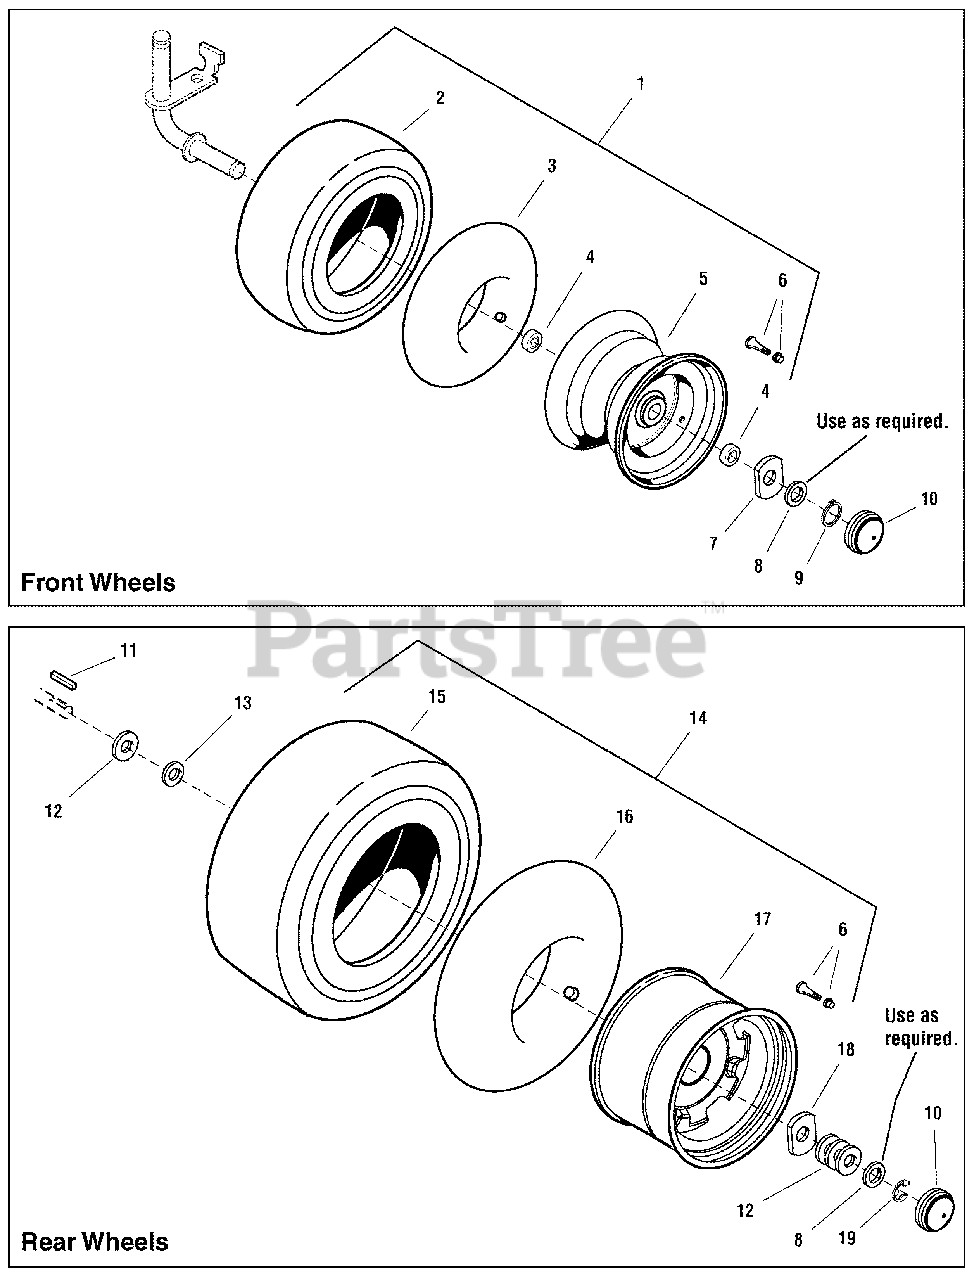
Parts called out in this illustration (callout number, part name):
1	WHEEL & TIRE ASSEMBLY, Front, (Includes Ref. Nos. 2, 3, 4, 5, & 6)
2	TIRE, 15 x 6, Super Turf
3	TUBE, Tire, Front, 4.10/3.50
4	BEARING, Ball
5	WHEEL, 4-1/2" x 6"
6	VALVE STEM & CAP ASSEMBLY
7	WASHER, Flat 1 (Double D)
8	WASHER, 1, (As Required for All Front)
9	RING, Retaining, External #98
10	CAP, Hub, Gray
11	KEY, Parellel, 3/16 x 3/16 x 1-1/2
11	KEY, Parellel, 3/16 x 3/16 x 2-1/2
12	WASHER, 3/4
13	WASHER
14	WHEEL & TIRE ASSEMBLY, (Includes Ref. Nos. 6, 15, 16 & 17)
15	TIRE, 22 x 10, 10 Super Turf
16	TUBE, Tire, 20 x 8, Rear
17	WHEEL, 7 x 9.97, W/ 3/4 OD Shaft
18	WASHER, Special
19	RING, "E" External
